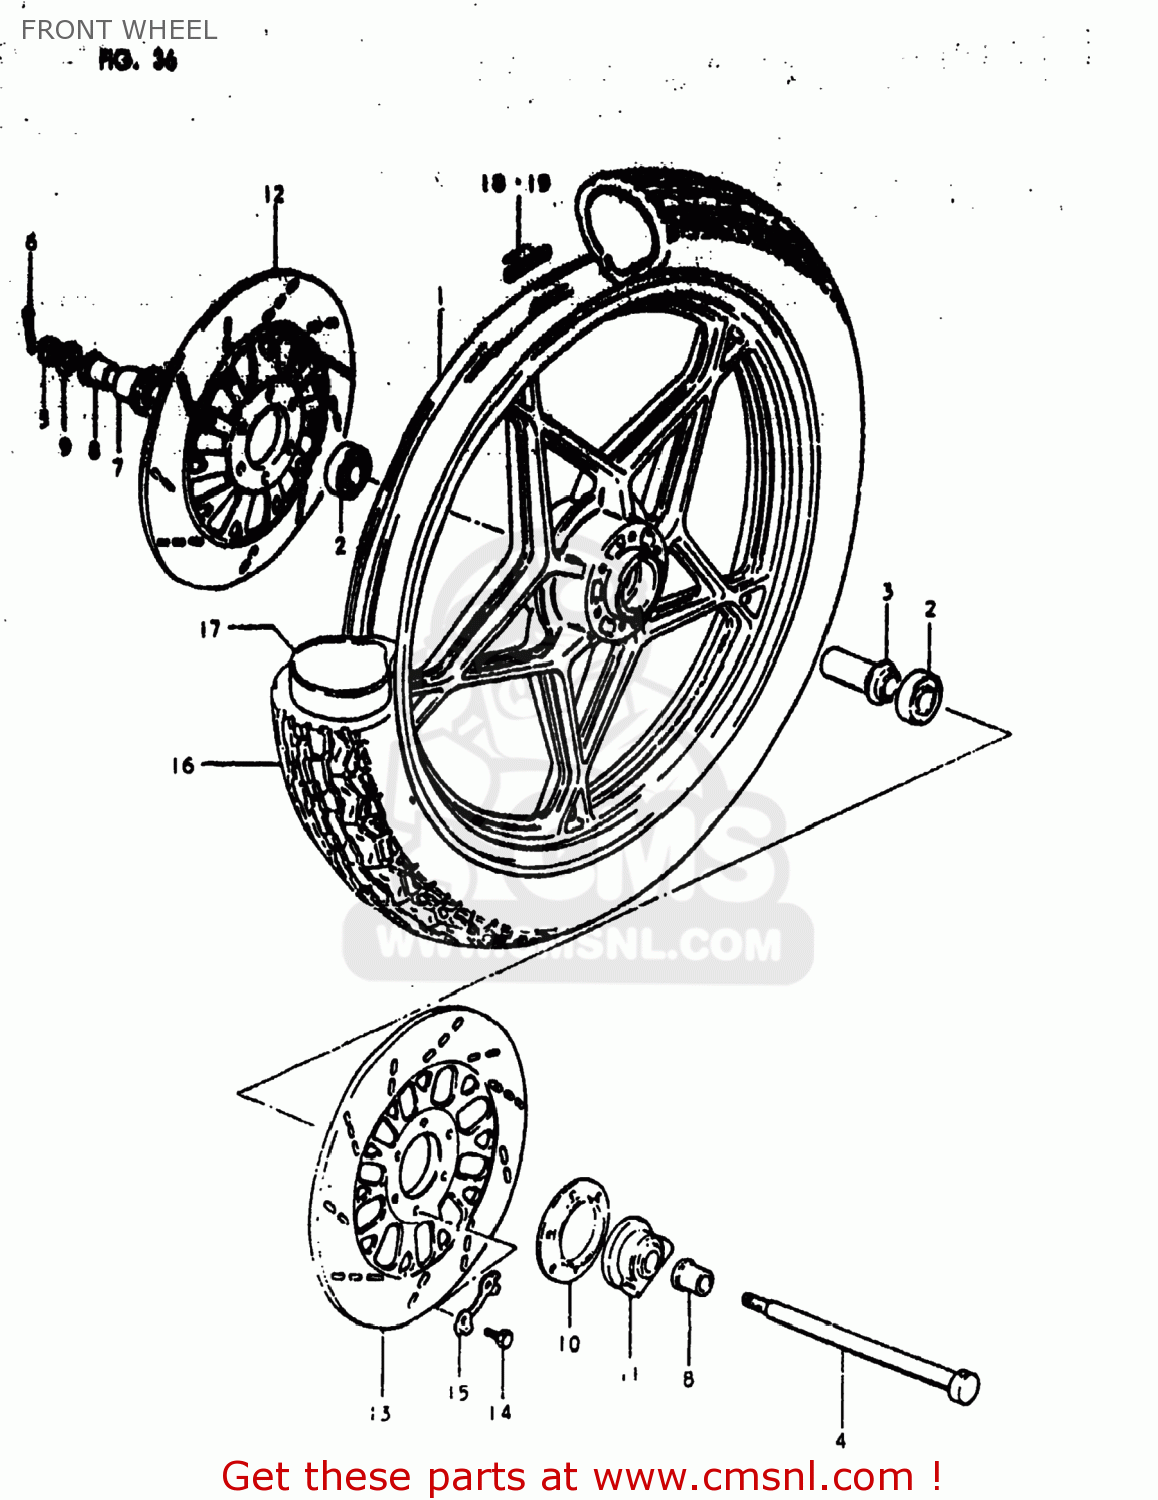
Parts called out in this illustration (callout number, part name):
1	WHEEL, FRONT
2	BEARING
3	SPACER,FR HUB BEARING
4	AXLE,FR
5	NUT 12MM
6	COTTER PIN
7	SPACER,FR AXLE,R
8	SPACER,FR AXLE,L
9	WASHER
10	DUST SEAL,SPEEDOMETER GEAR BOX
11	BOX ASSEMBLY,SPEEDOMETER GEAR
12	DISC,FR BRAKE,R
13	DISC,FR BRAKE,L
14	BOLT(8X25)
15	WASHER
16	TIRE,FRONT
17	TUBE,INNER
18	BALANCER,WHEEL
19	BALANCER,WHEEL
